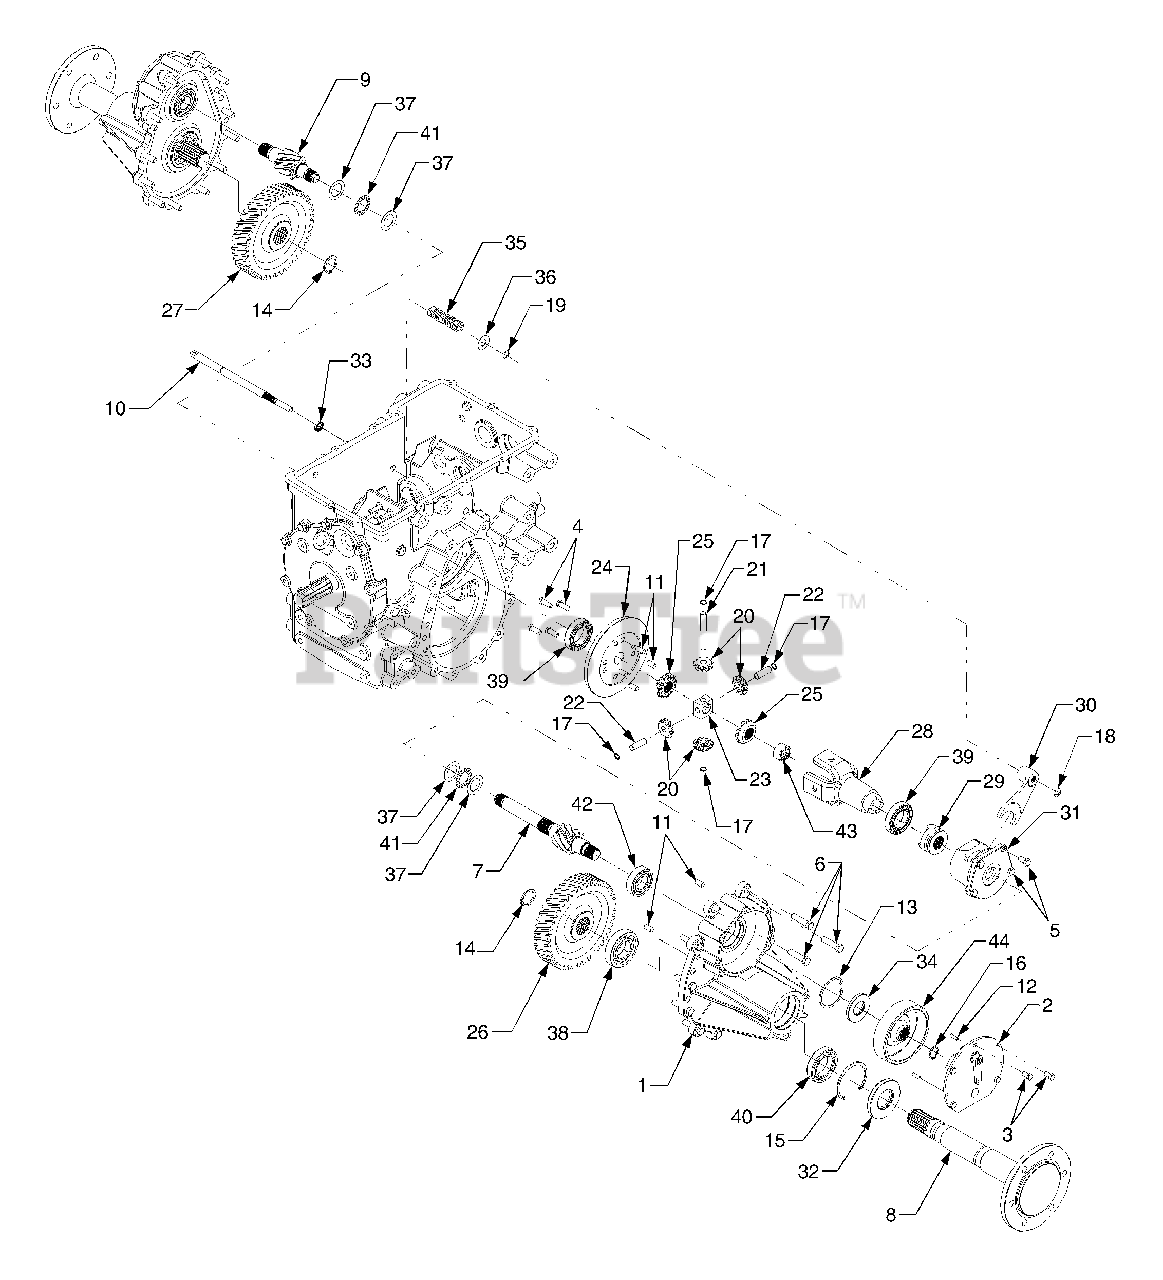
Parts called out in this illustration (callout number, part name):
1	Housing, Axle
2	Brake Assembly, Drum
3	Screw, Hex Cap Lock, 5/16-18 x .625 GR5
4	Screw, Socket Hd. Cap, 3/8-16 x 1.0
5	Screw, Hex Cap Lock, 3/8-16 x .75 GR5
6	Screw, Hex Cap Lock, 7/16-14 x 1.75 GR5
7	Shaft, Axle Stub RH
8	Shaft, Axle
9	Shaft, Axle Stub LH
10	Shaft, Differential Lock Actuator
11	Pin, Dowel, .3752 x .75
12	Pin, Dowel, .25 x .75
13	Ring, Retaining
14	Ring, Retaining
15	Ring, Retaining
16	Ring, Retaining
17	Ring, Retaining
18	Clip, Rotor
19	Ring, Retaining
20	Gear, Differential, 10T
21	Shaft, Cross
22	Shaft, Cross
23	Block, Differential Pinion
24	Gear, Bevel, 65T
25	Gear, Miter, 14T
26	Gear, Drop Axle, 42T RH
27	Gear, Drop Axle, 42T LH
28	Carrier, Differential
29	Collar, Differential Lock
30	Yoke, Differential Lock
31	Cover, Bearing
32	Seal, Oil, 50mm x 75 mm x 10mm
33	Seal, Oil
34	Seal, Oil, 1.181 x 2.453 x .276
35	Spring, Compression
36	Washer, Flat, .56 x 1.0 x .04
37	Washer, Thrust, 1.12 x 1.75 x .03
38	Bearing, Ball
39	Bearing, Ball
40	Bearing, Ball
41	Bearing, Thrust
42	Bearing, Ball
43	Bearing, Needle
44	Drum, Brake
